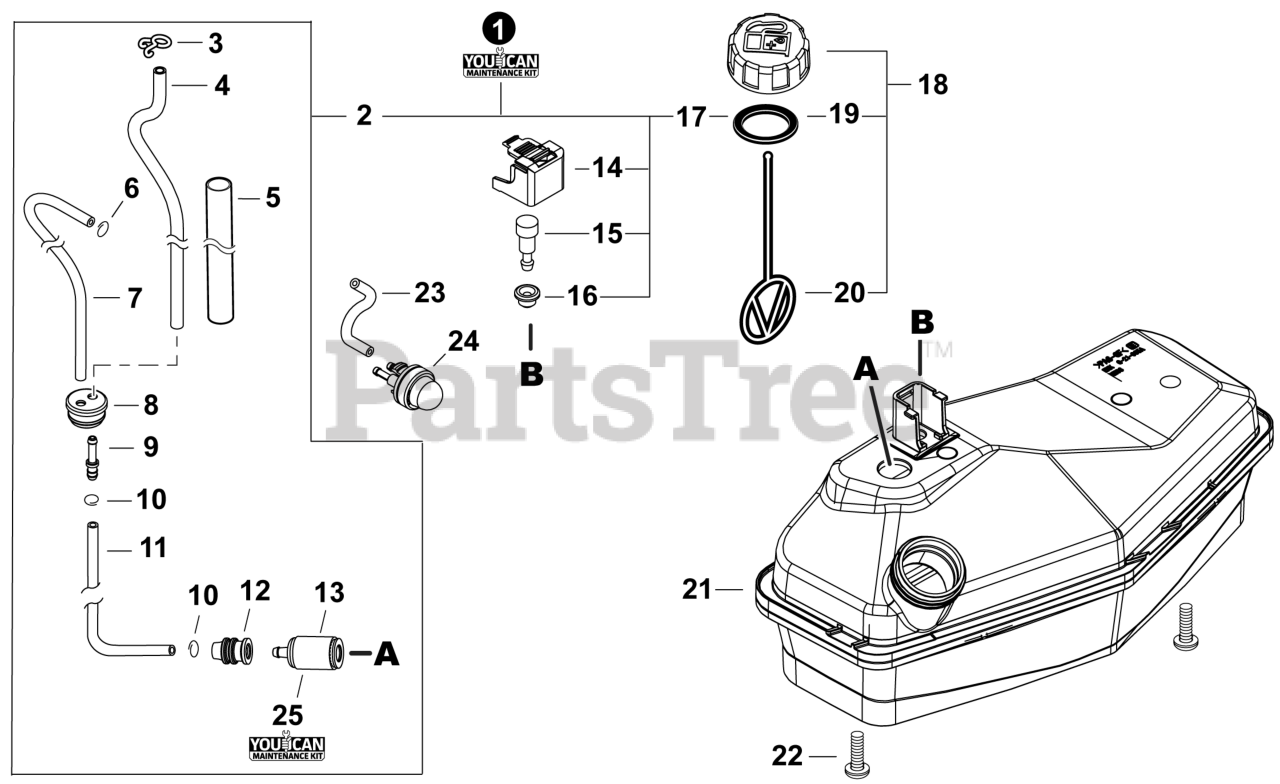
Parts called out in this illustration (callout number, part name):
1	FUEL SYSTEM KIT - YOUCANT
2	FUEL PIPE ASSY
3	CLIP, SPRING 5.2
4	PIPE, FUEL 3.5x6x160 CLEAR
5	TUBE, INSULATOR 10x12x70
6	CLIP 5.5
7	PIPE, FUEL 2.4x5x153 BLACK
8	GROMMET, FUEL
9	CONNECTOR, PIPE 5x3.5
11	PIPE, FUEL 3x5x165 BLACK
13	FILTER, FUEL
14	COVER, VENT
15	VENT ASSY
16	GROMMET, FUEL
17	GASKET, FUEL CAP
18	CAP ASSY, FUEL
19	GASKET, FUEL CAP
20	CONNECTOR, CAP L= 123
21	TANK, FUEL
22	BOLT, TORX 6x20
23	PIPE, FUEL 2.4x5x65 BLACK
24	BULB, PURGE
25	TUNE-UP KIT - YOUCANT
